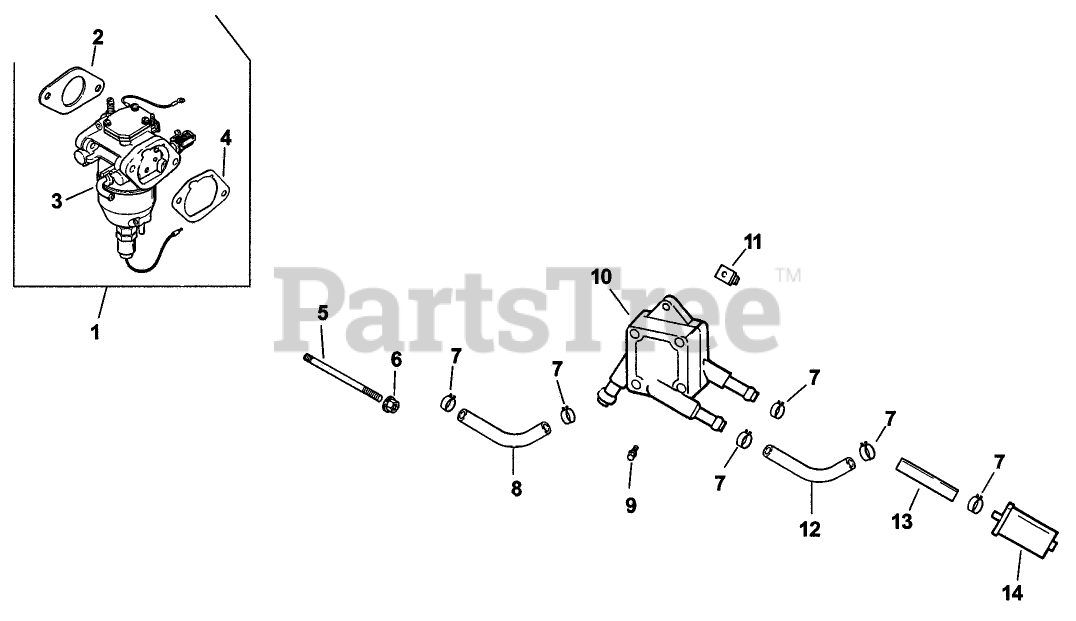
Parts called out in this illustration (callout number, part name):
1	Kit, carburetor with gaskets (Includes 2-4)
2	Gasket-carburetor
3	Carburetor assembly (For information only not available separately)
5	Stud
6	Nut-Hex Flange
7	Clamp
8	Line, fuel 10-1/2
9	SCREW-TAP (M6X1.7X18)
10	Pump, fuel-pulse
11	Nut-Plastic
12	Line, fuel 9"
13	Filter-Fuel
14	Filter-Fuel
